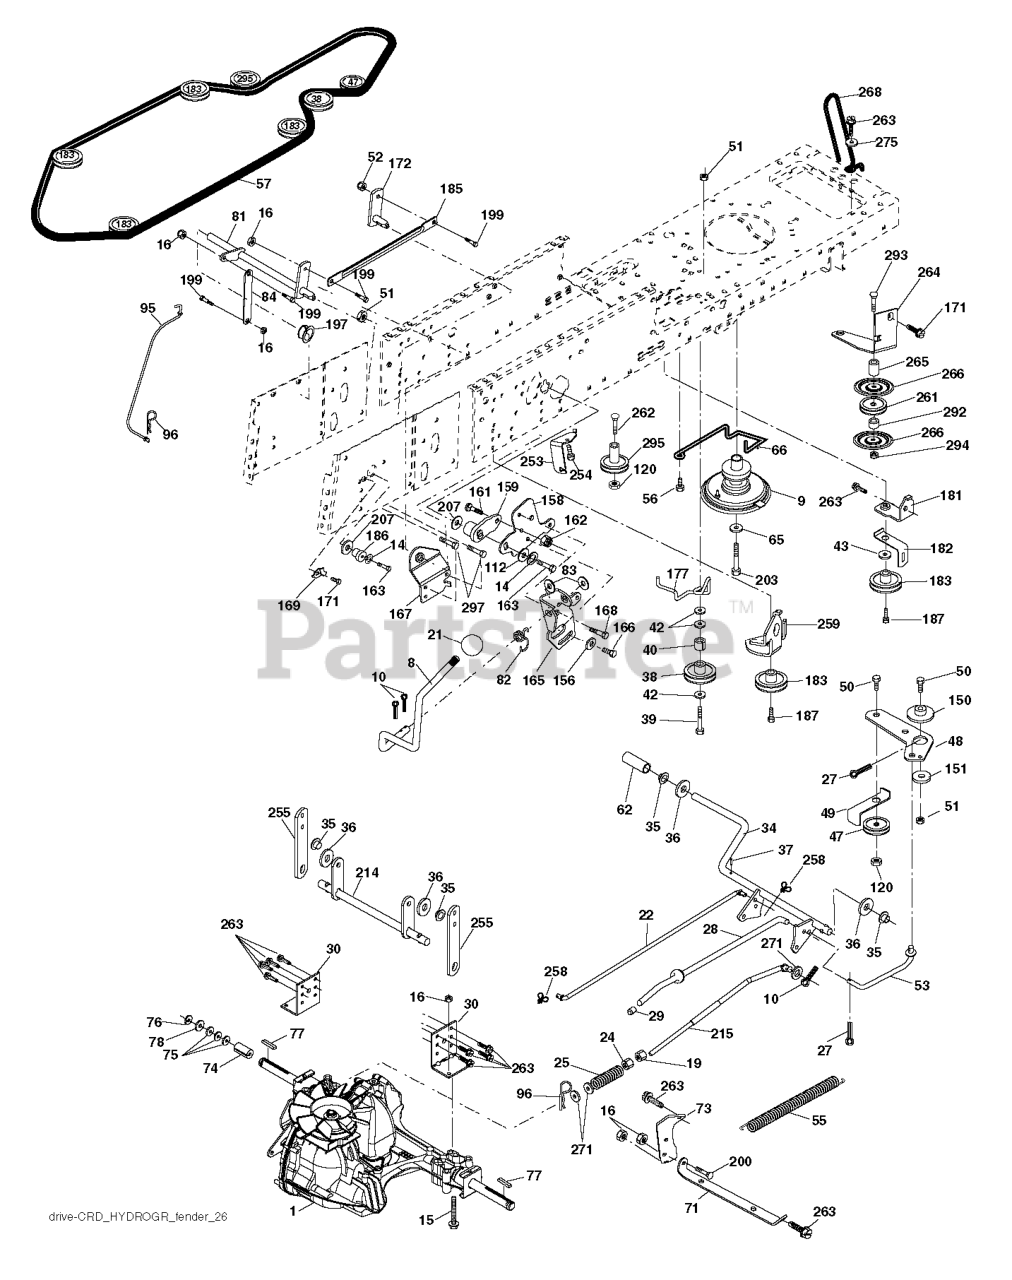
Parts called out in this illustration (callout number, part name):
8	ROD SHIFT FENDER ADJUST LT
10	PIN COTTER
14	LOCKWASHER
15	BOLT HEX 5/16-18 GR 5
16	NUT.71038.31-18.HEX.NYLOCK
19	NUT
21	KNOB T (1/2-HOLE)
22	ROD
24	NUT
25	SPRING BRAKE ROD
27	COTTER PIN
28	ROD, PARKING BRAKE
29	PLUNGER CAP
30	BRKT, TRNSXLE MNT 20"
34	SHAFT, FOOT PEDAL
35	BEARING.NYLON
37	DRIVE PIN
38	PULLEY.FLAT
42	WASHER
47	IDLER PULLEY
48	BELLCRANK, CLUTCH
49	RETAIN BELT
50	BOLT.3/8-16X1.50
52	LOCKNUT
53	LINK.CLUTCH.7.66.2005
55	SPRING, RETURN LT
56	SCREW.3/8-16
57	V-BELT 113"
62	PEDAL COVER T
65	LOCKWASHER
66	KEEPER BELT ENGINE
71	STRAP TORQUE LH HYDRO
73	STRAP TORQUE RH HYDRO
74	SPACER AXLE
77	SQUARE KEY
81	ASM.CROSS.SHAFT.REAR.CRD.0510
82	SHIFT SPRING
83	WASHER
84	LINK.PNT.TRANSAXLE.0510.CRD
95	LINK
96	RETAINER M
120	NUT LOCK FLG 3/8-16 UNC
150	BUSHING.BELLCRANK.GRD.DR
151	WASHER 12/32X2X10GA
156	WASHER.SRRTD.5/16
158	BRACKET.SHIFT.MOUNT
161	BOLT
162	NUT.CROWNLOCK.1/4
165	BRACKET.PIVOT.LEVER
166	CAPSCREW.HXHD.FLG.5/16-18X.625
167	BRACKET.SUPT.SHIFT.CRD
168	BOLT.SHOULDER.5/16-18X
169	PLATE.FASTENING.CROSS.SHAFT
172	LINK
181	BRACKET
182	BELT GUIDE
183	PULLEY.V-IDLER.
185	LINK
186	HUB.TAPERED.ROUND.CRD
187	BOLT.5/16-18X1.25
197	NYLINER SNAP 5/8" ID
199	BOLT SHOULDER 5/16-18 UNC
203	BOLT.HEX.7/16-20 X 5
207	WASHER NYL
214	LEVER
215	ROD
254	SCREW 3/8-16X1
255	SHAFT
258	CLIP RETAINER
259	BRACKET
261	FLAT IDLER PULLEY
263	SCREW, 3/8-16X3/4
264	BRACKET.IDLER.CHASS.NORAM.2010
266	PROTECTOR
268	GUARD MUFFLER
271	WASHER
275	WASHER
292	SPACER
293	BOLT.RDHD SQNK 3/8-16 X 3-1/2
294	NUT.HEX.3/8-16
295	PULLEY IDLER COMPOSITE
297	SCREW LT.3/8-46X5/8
